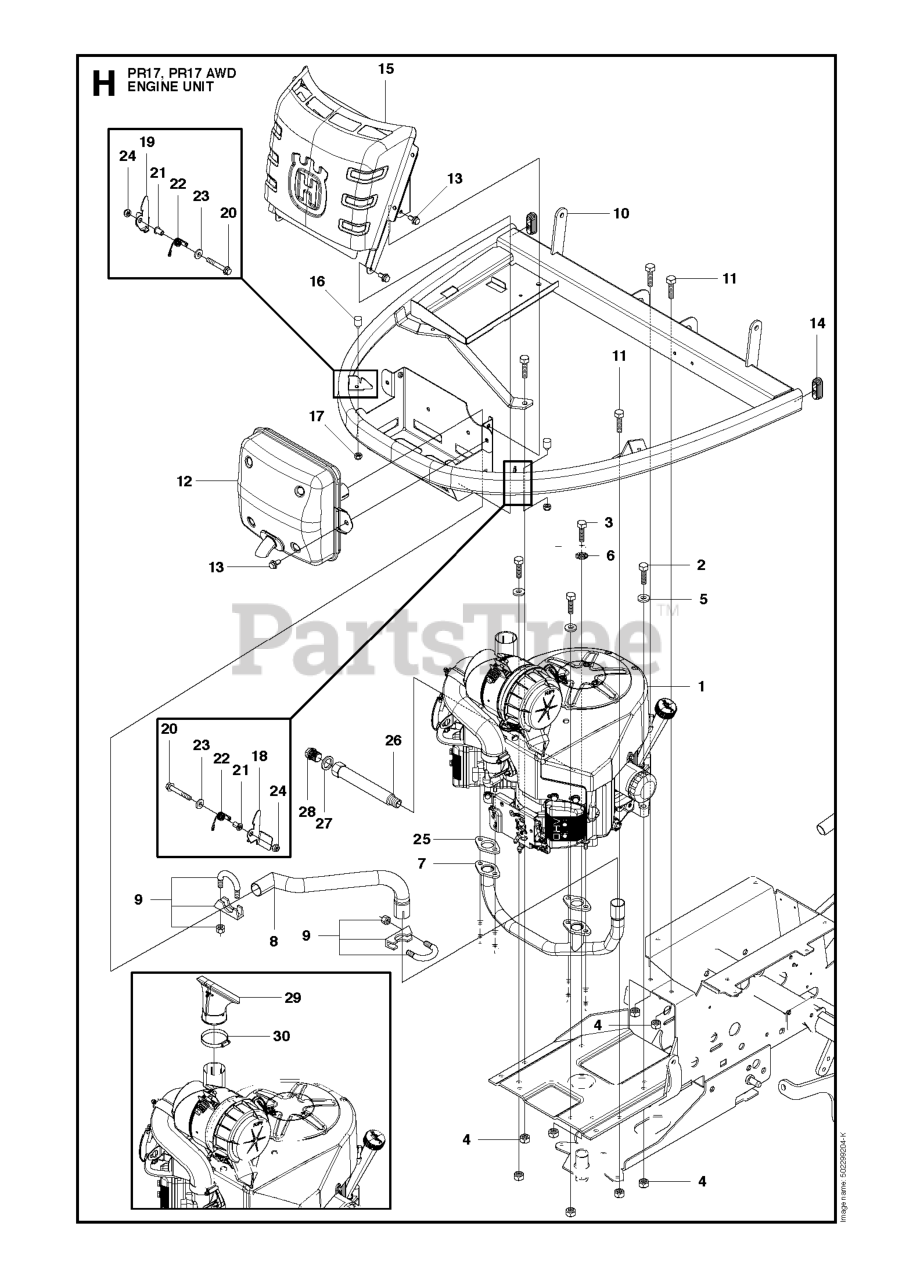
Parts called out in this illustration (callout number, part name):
4	LOCKNUT M8
5	WASHER BRB 8.4X17
9	CLAMP
13	SCREW EHHFM
17	LOCKNUT M5
23	WASHER - 26X6.5X1.6
24	LOCKNUT M6
